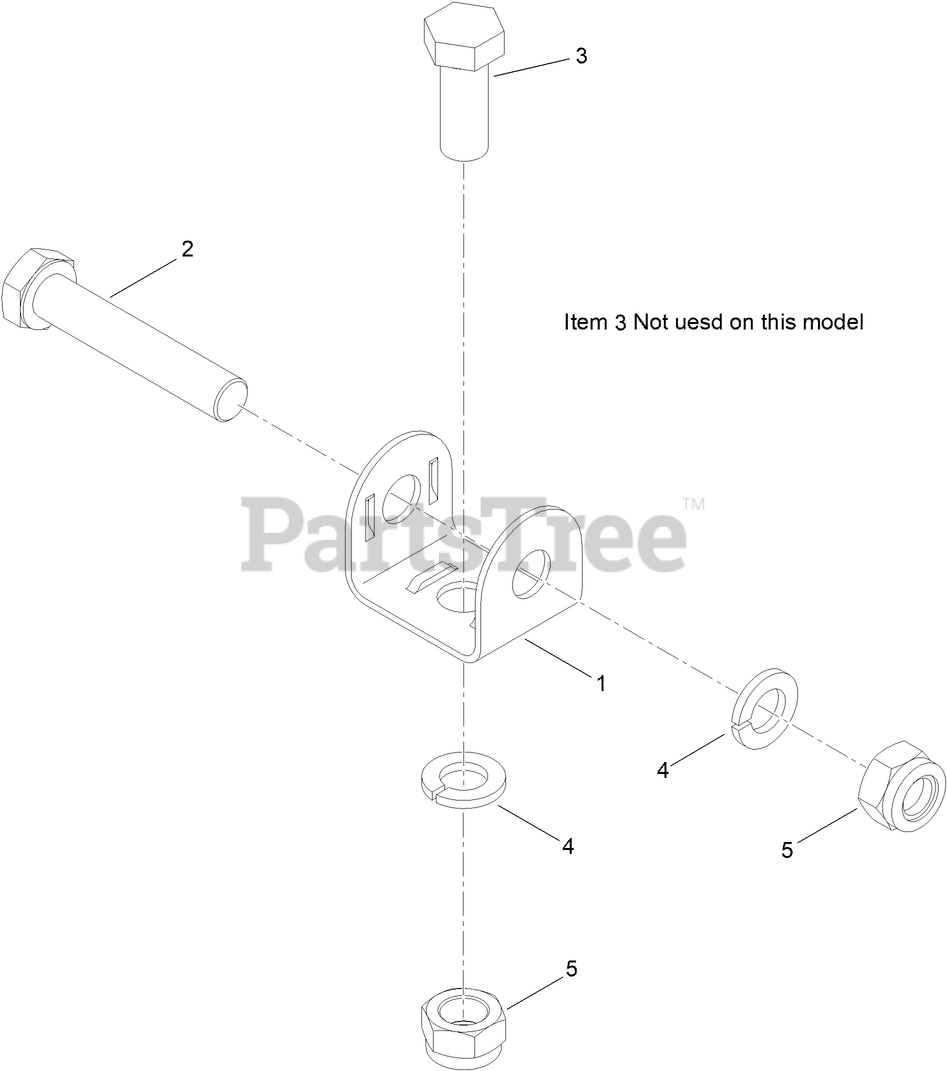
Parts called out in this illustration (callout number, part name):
1	MOUNT-LIGHT
2	SCREW-HH
3	SCREW-HH
4	WASHER-LOCK
5	NUT-HEX
